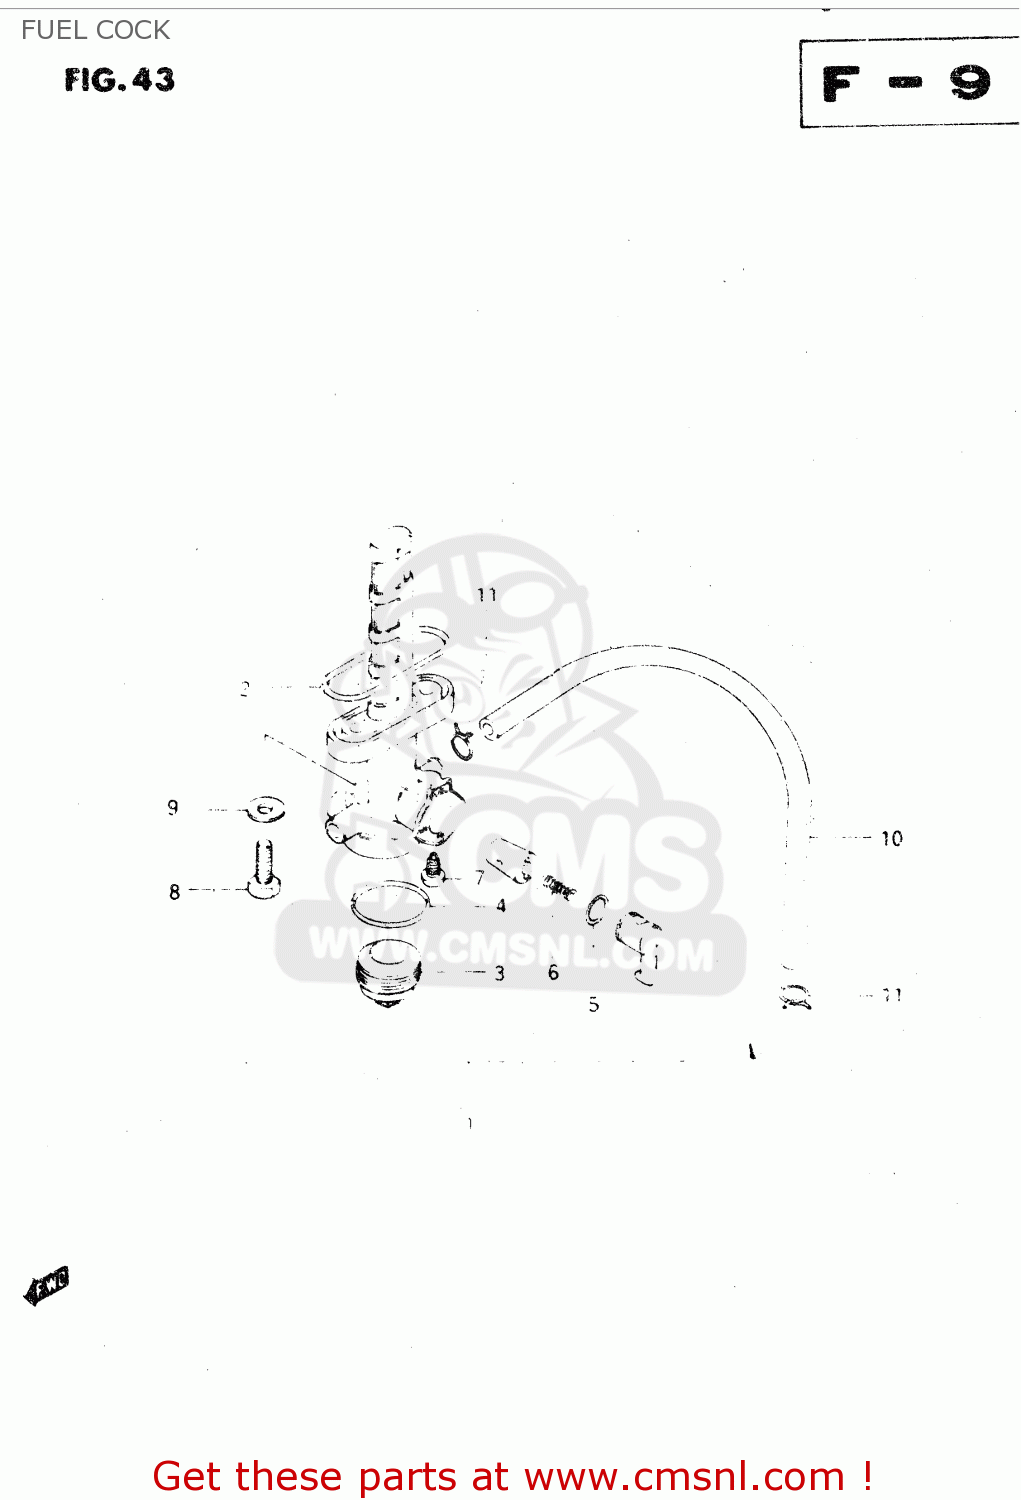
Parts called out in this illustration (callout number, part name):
1	COCK ASSEMBLY,FUEL
2	O RING,FUEL COCK
3	CUP,STRAINER
4	GASKET,FILTER (NAS)
5	O-RING
6	SPRING
7	SCREW
8	BOLT(6X20)
9	GASKET
10	HOSE
11	CLIP
